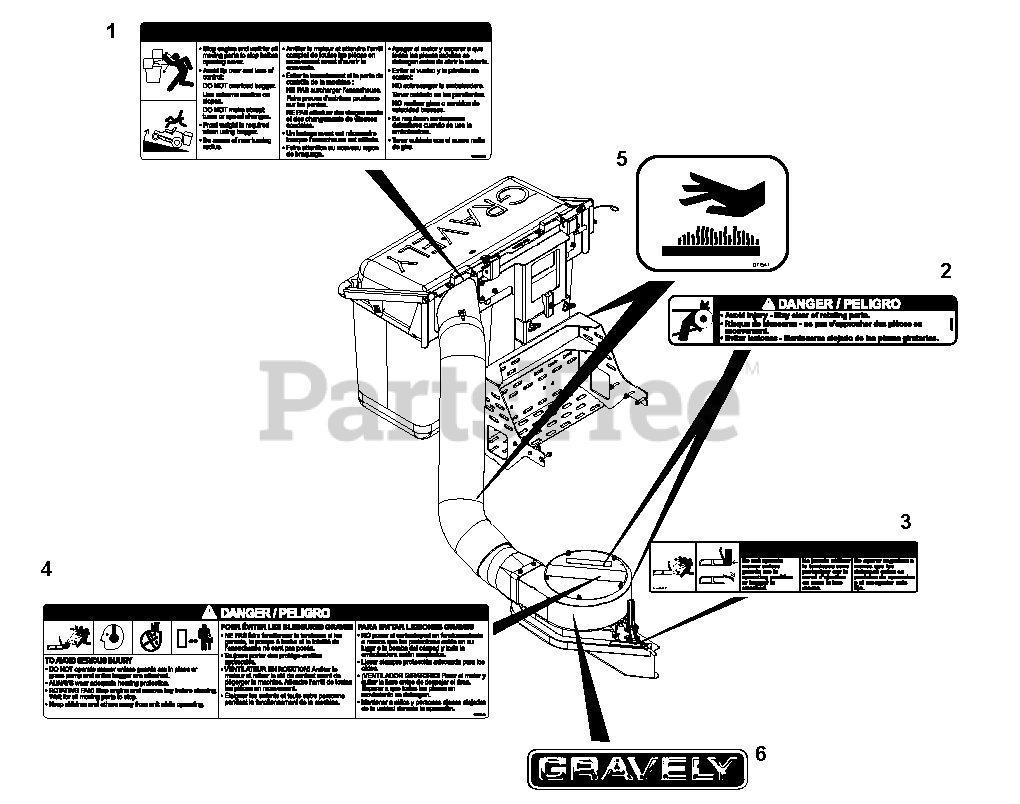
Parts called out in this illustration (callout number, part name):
1	DECAL, WARNING, BAGGER COVER
2	DECAL, DANGER
3	DECAL, WARNING
4	DECAL, CAUTION, GRASS PUMP
5	DECAL, HOT SURFACE
6	DECAL, GRAVELY
